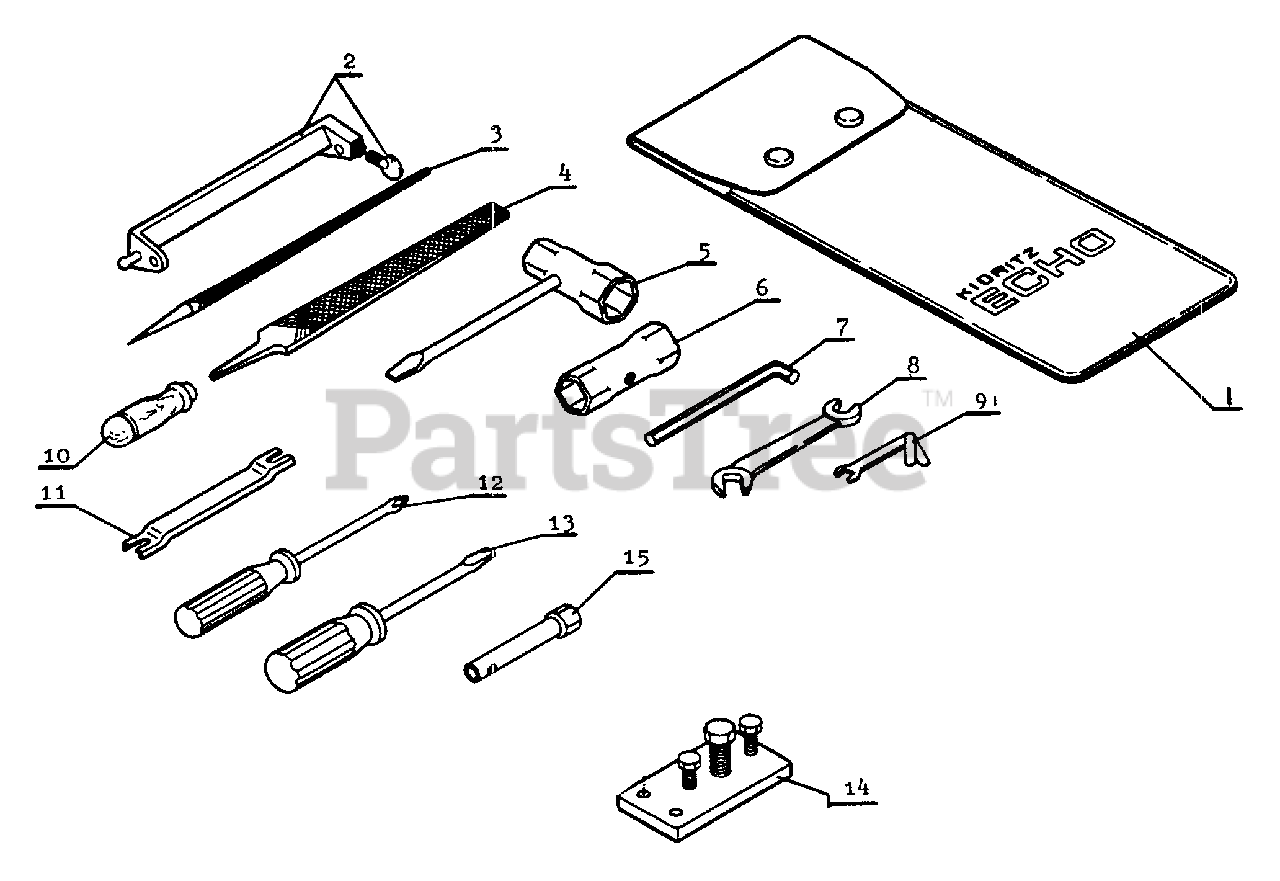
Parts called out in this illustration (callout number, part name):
1	BAG, TOOL
2	FILE HOLDER
3	ROUND FILE
4	FLAT FILE
5	T-WRENCH 13×19×180
6	BOX SPANNER - 14×17
7	WRENCH, ALLEN 4 MM
8	SPANNER - 8×10
9	MAGNETO SPANNER
10	FILE GRIP
11	GAUGE, DEPTH
12	SCREWDRIVER - CROSS HEAD
13	SCREWDRIVER
14	MAGNETO PULLER
15	BOX SPANNER - 8
